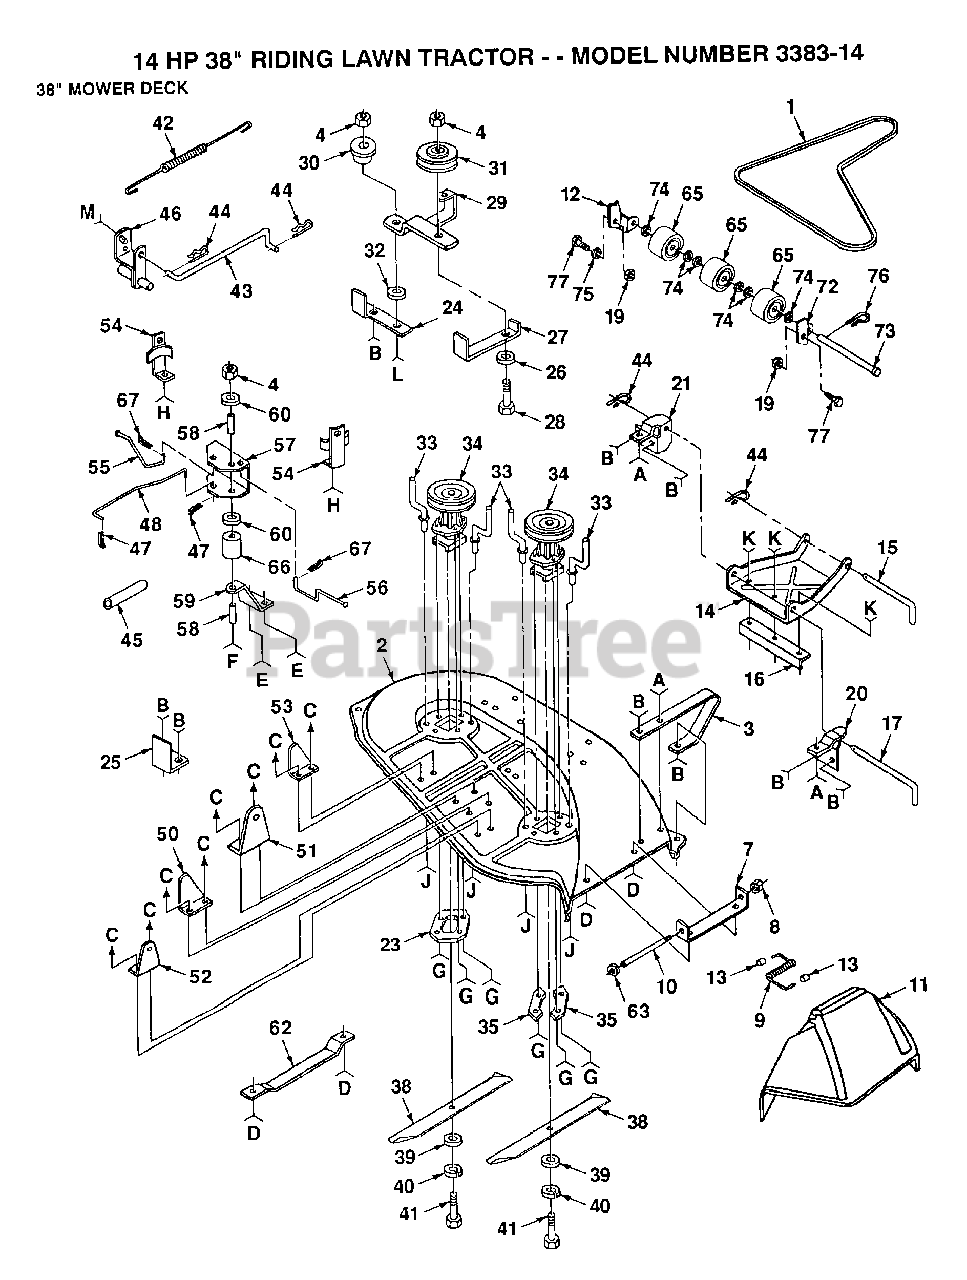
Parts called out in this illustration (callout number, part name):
1	BELT-V.79.1.MWR
8	NUT PUSH M
10	ROD-HINGE T
11	DEFLECTOR-SHLD T
12	BRACKET LH T
13	CAP-SLEEVE LT
14	LINK.PARALLEL
15	"ROD, FRT. PARAL T"
16	LINK STOP
17	HINGE PIN T
20	BRACKET RH LT
21	BRACKET LH T
23	BRACKET RH T
24	SUPPORT ARM T
25	STOP T
26	WASHER
30	SPACER RETAINER
32	"WASHER, WEAR LT"
33	BELT KEEPER LT
35	SUPPORT PLATE LT
38	"BLADE.38"" HI-LI"
39	WASHER
41	BOLT.3/8-24X1-1/2
44	SPRING.RETAINER
45	SPACER T
48	ROD BRAKE LT
52	"BRKT,SUSP RH T"
53	"BRKT,SUSP REAR LH"
54	BRAKE LT
55	"ROD, BRAKE LH LT"
56	ROD BRAKE LT
57	"BRK,BRAKE,PVT LT"
58	SPACER BRAKE LTV
59	BRACKET SUPT LTV
60	WASHER
62	RUNNER-LH M
63	WASHER
65	ROLLER T
72	SUPPORT T
73	PIVOT PIN T
74	WASHER T
76	COTTER PIN
77	BOLT
